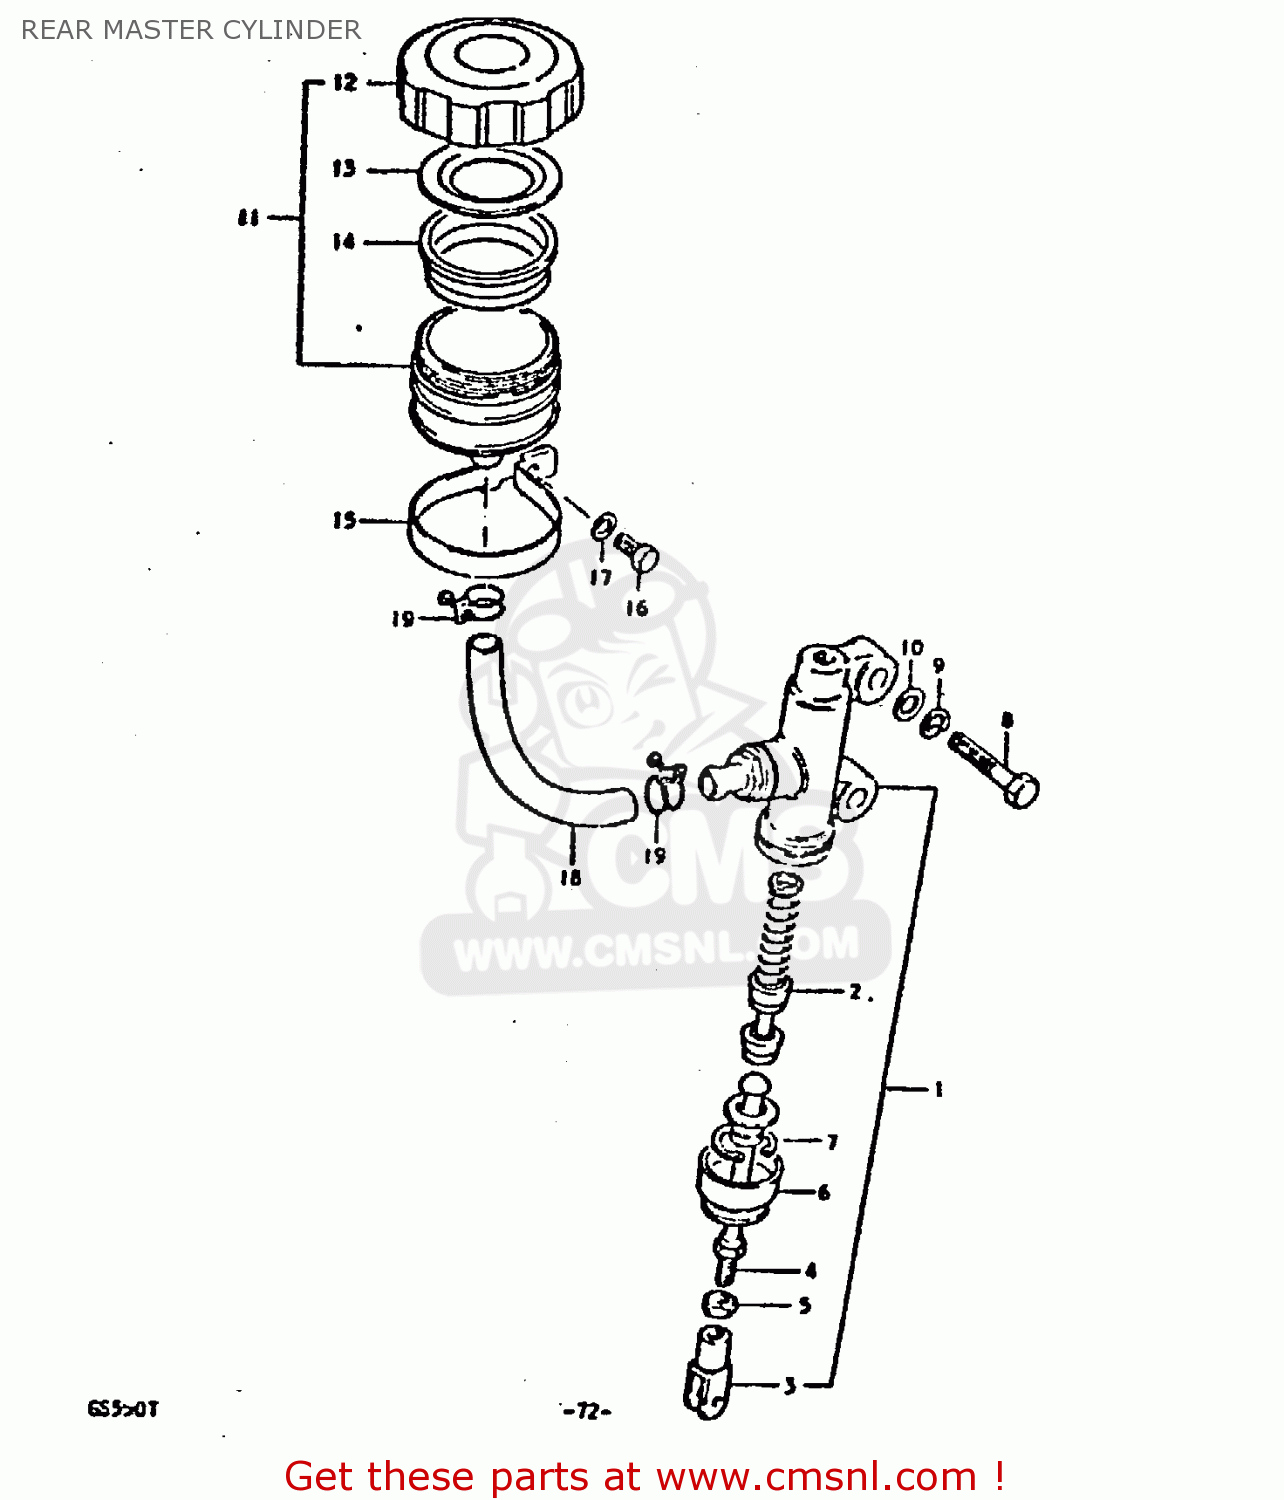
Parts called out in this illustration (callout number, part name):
1	CYLINDER ASSEMBLY,REAR MASTER
2	PISTON/CUP SET
3	YOKE
4	ROD,PUSH
5	NUT
6	BOOT
7	CIRCLIP
8	BOLT (8X30)
9	LOCK WASHER
10	WASHER
11	TANK ASSEMBLY,RESERVOIR
12	CAP
13	PLATE,DIAPHRAGM
14	DIAPHRAGM
15	CLAMP
16	BOLT, UPPER
17	LOCK WASHER
18	HOSE,RESERVOIR TANK
19	CLAMP
